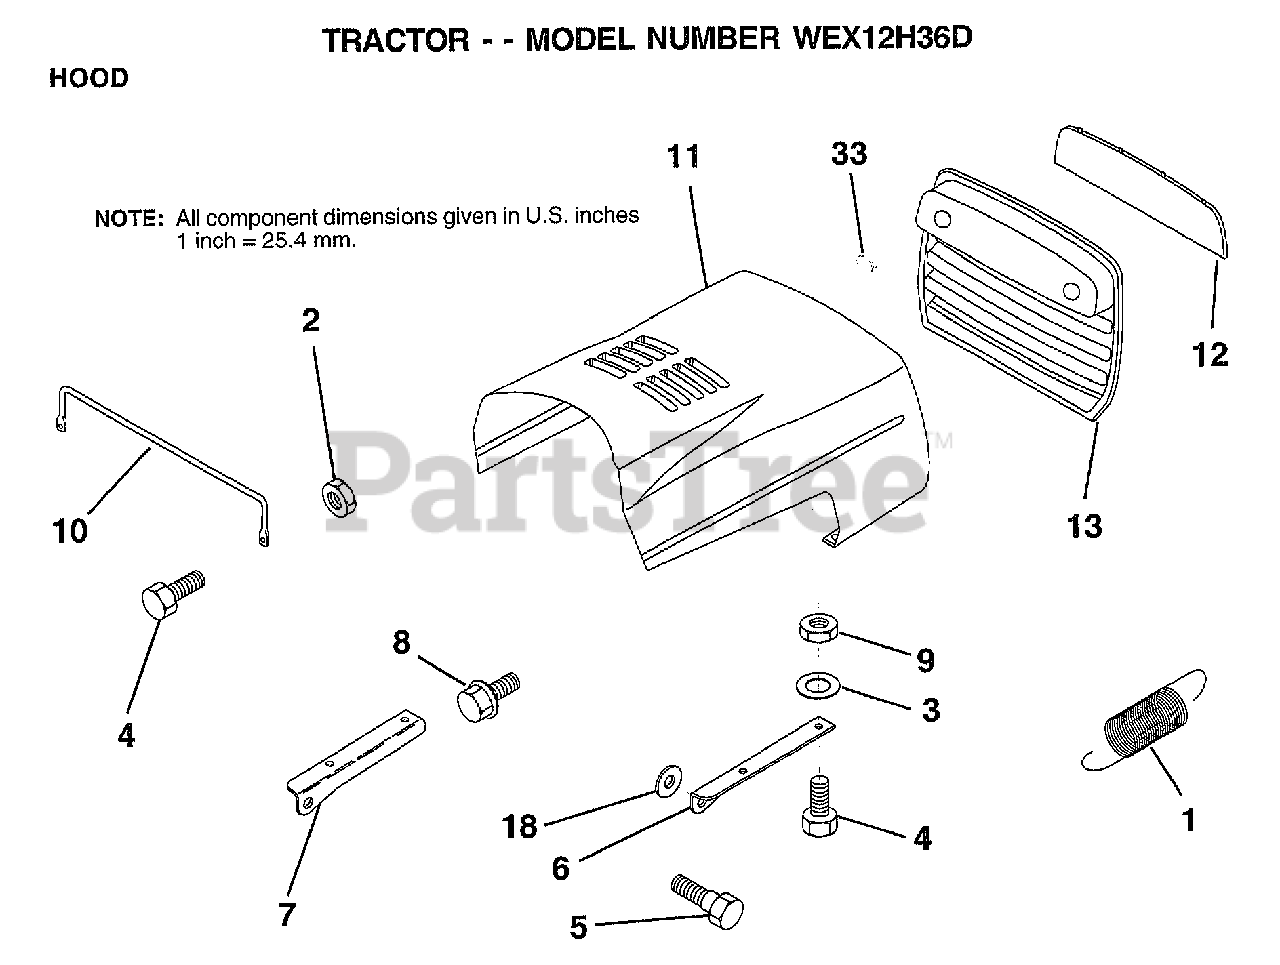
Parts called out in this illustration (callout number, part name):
1	EXT SPRING
2	NUT
3	WASHER
5	BOLT.SHLD.5/16-18
6	BRKT HOOD RH
7	BRKT HOOD LH
8	"SCREW,HWHD.HI-LO#13-16X3/4"
9	NUT
10	"BRACE,HOOD"
11	HOOD.IMPREG.MS550
12	LENS
13	GRILL
18	WASHER
